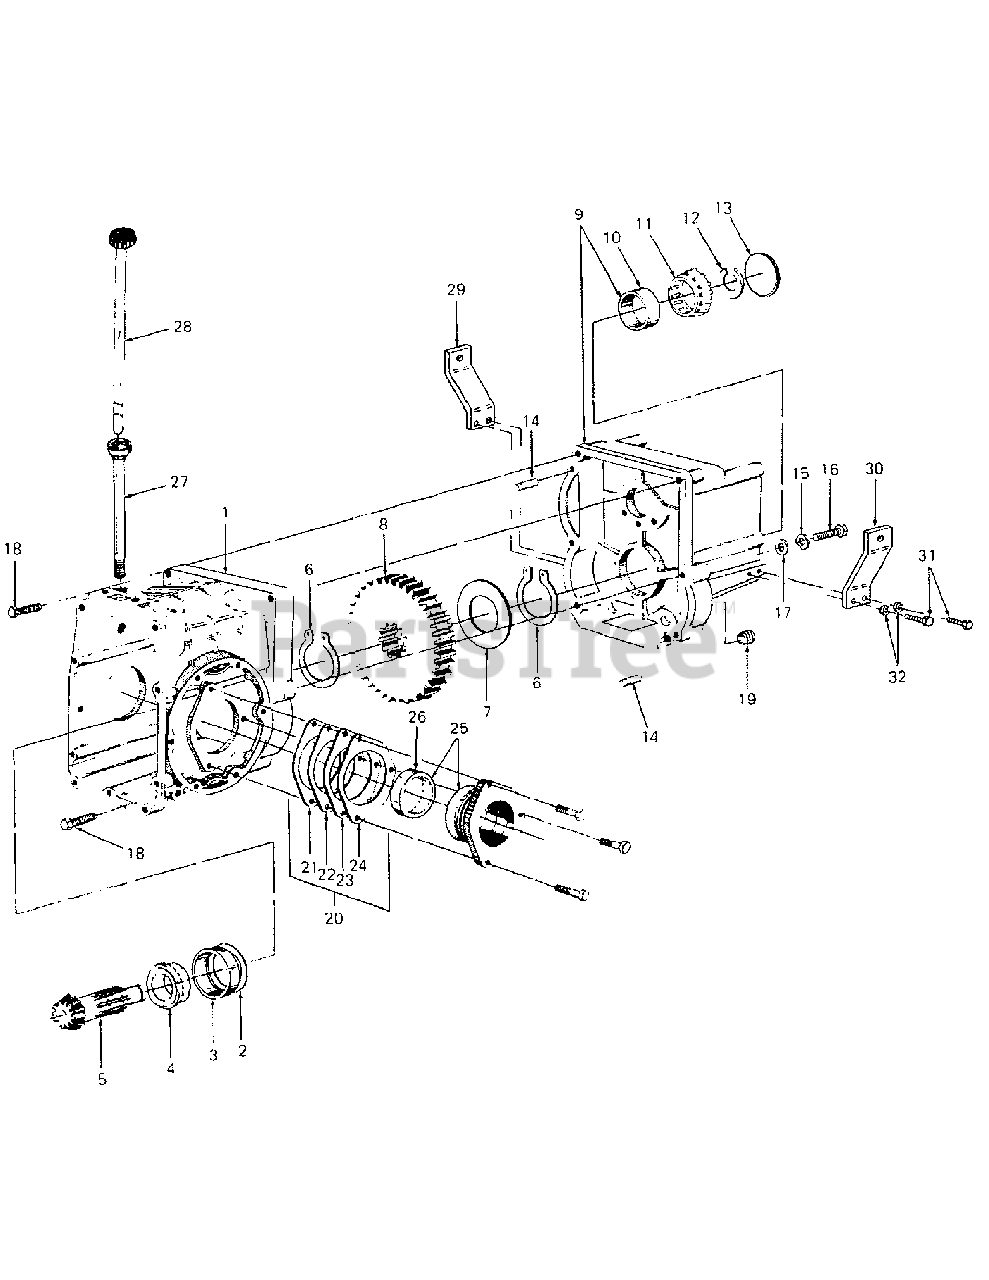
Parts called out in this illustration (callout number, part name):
1	Housing Assy, Rear Transaxle
2	Shim, Rear Bearing Cup, .004 Thk
3	Cup, Roller Bearing
4	Cone, Roller Bearing
5	Shaft, Bevel Pinion
6	Ring, Retaining, 1.312 Dia
7	Spacer, Gear
8	Gear, Reduction - 66T
9	Housing Assy, Adapter w/Cup
10	Cup, Roller Bearing
11	Cone, Roller Bearing
12	Retainer, Front Bearing, .125 Thk
13	Plug, Expansion, 2.12 OD
14	Pin, Dowel, 3/8 Dia X 5/8 Lg
15	Washer, Spring, .445 X.75 X.017 Thk
16	Screw, Hex Cap, 7/16-14 X 2.5 Lg GR5
17	Washer, Flat, .46 X .875 X .060 Thk
18	Bolt, Hex Patch, 7/16-14 X 1.75 Lg GR5
19	Plug, Drain
20	Shim Package
21	Shim, Bearing Retainer, .004 Thk
22	Shim, Bearing Retainer, .007 Thk
